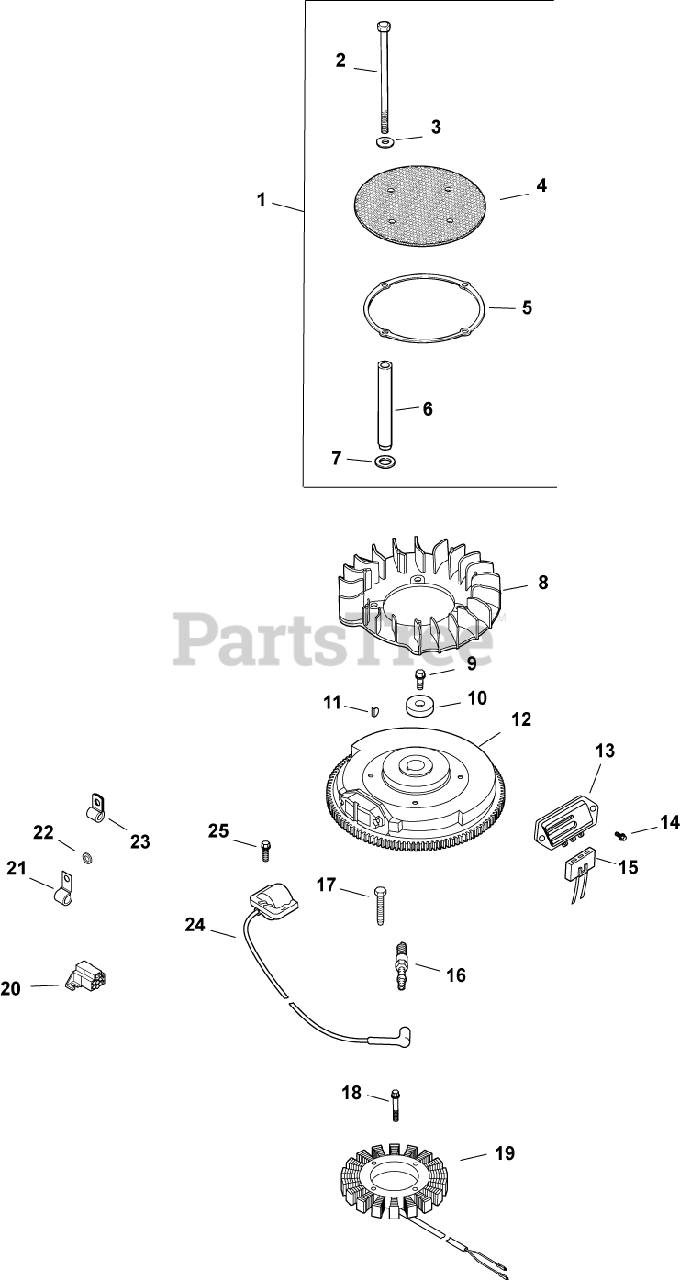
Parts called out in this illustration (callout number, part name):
1	KIT, CHOPPER SCREEN
2	SCREW, CAP M6X1.0X99.5
3	WASHER, FLAT 1/4" (O.D. 5/8")
4	SCREEN, GRASS
5	RING, SUPPORT USE 25 141 08-S
7	WASHER, SPRING 10 MM
9	SCREW, FLG M10X1.5X45 - (#25086361S)
10	WASHER, FLAT 13/32"
11	KEY, 3/16" X 5/8"
12	FLYWHEEL, PAINTED-USE 24 025 59-S
13	REG/RECTIFIER (20/25 AMP)-USE 25 403 20-
14	SCREW, PHL HD #11-16X7/8"
15	CONNECTOR, BODY (KM)-USE 25 155 41-S
16	PLUG, SPARK (PRO SERIES)
17	SCREW, M5X0.8X25 - (#25086402S)
18	SCREW, SKT SET #10-24X1/4"
19	KIT, 15 / 20 AMP STATOR
20	CONNECTOR
21	CLIP, CABLE
22	WASHER, FLAT 1/4" (O.D. 1/2")
23	CLIP, TUBE & WIRING (KM)
24	KIT, MODULE IGNTN (CDI FIXED)
25	SCREW, FLG THD FRM M5X.8X20-(#25086399S)
